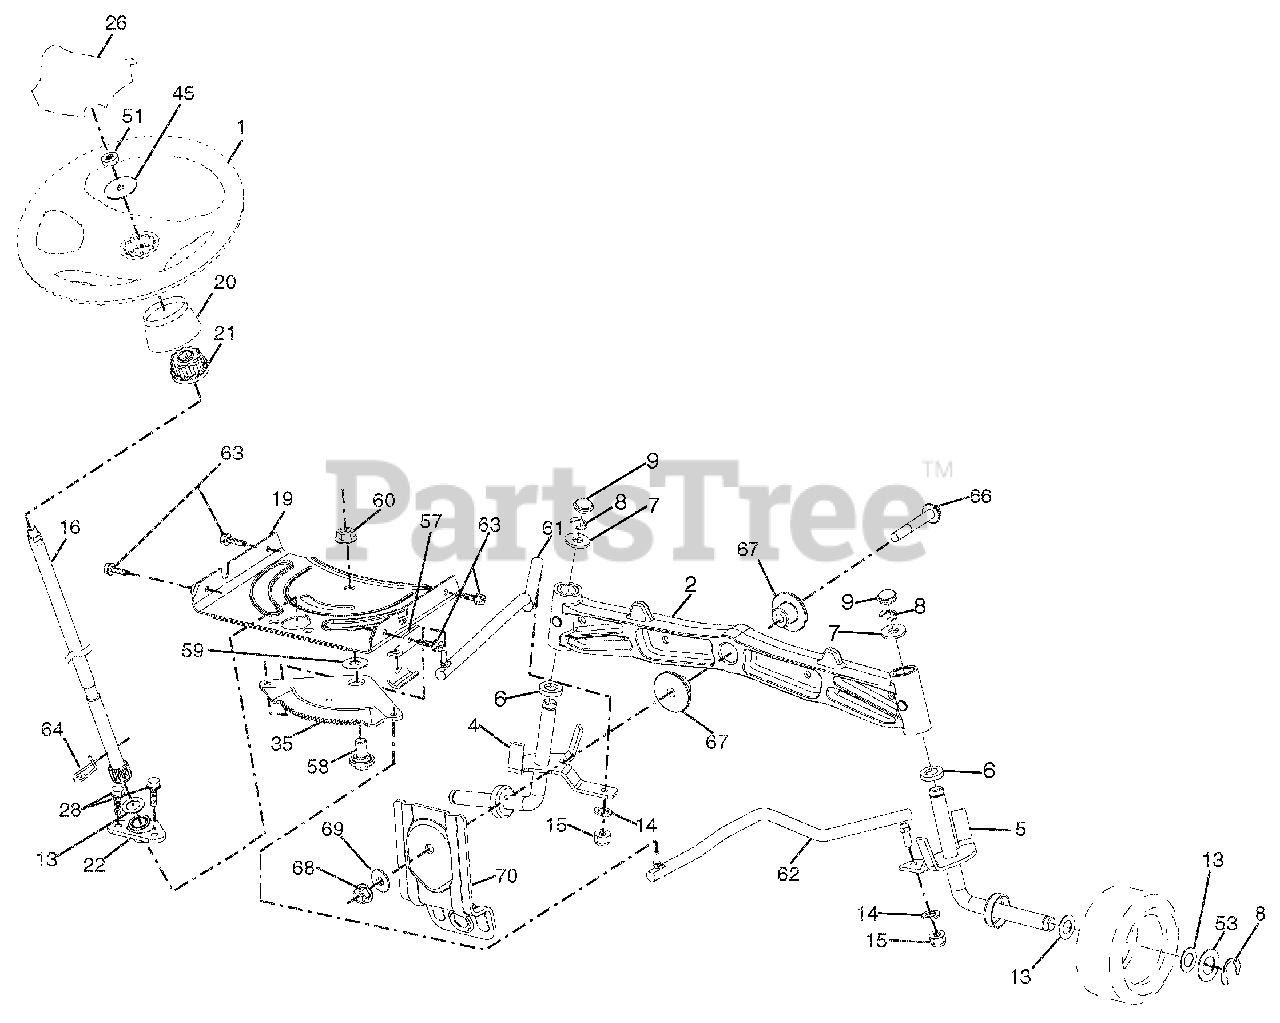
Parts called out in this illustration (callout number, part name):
1	WHEEL STEERING
2	AXLE.CAST IRON
4	SPINDLE.WELDED.LH.15"TEX
5	SPINDLE.WELDED.RH.15"TEX
6	WASHER.THRUST..75 X 1.230
7	WASHER.25/32 X 1-5/8 X 16GA.
8	RING.KLIP.#T5304-75
9	CAP.SPINDLE.FR.TOP.BLK.
13	WASHER.25/32 X 1 1/4 X 16 GA.
14	Washer, Lock 3/8
15	NUT.CROWNLOCK.3/8-24
16	SHAFT.STEER.3/4 TEX.NON-PLATED
19	PLATE.STEER.DDL.NLT/NGT
20	BOOT.STEERING.TEX ELITE.428
21	ADAPTER.WHEEL.STRG..760
22	STEERING SUPT. LOWER
26	CAP.WHL.STRG.HRS/SRS.BLACK
28	SCREW.HEXWSH THDR3/8-16X3/4.BL
35	GEAR SECTOR.PLATE.DDL.NLT/NGT
45	WASHER.9/16ID X 2-3/8OD.12GZIN
51	NUT.HEX.JAM.TOPLOCK.1/2-20 UNF
53	WASHER.HARDEN..793 X 1.637X060
57	BRACKET.UPSTOP.TEX
58	BOLT.SHOULDER.SECTOR.PIVOT.CFM
59	WASHER.THRUST.SECTOR.STEER.NLT
60	NUT.FLANGE LOCK.5/8-11
61	DRAGLINK.LH.BALLSTUD.DDL.
62	DRAGLINK.RH.BALLSTUD.DDL
63	SCREW.5/16-18X3/4.SMGML.TAP/BL
64	RETAINER.CLIP.SPRING.STEERING
66	BOLT.HEX.FGHD.7/16-14 X 3.SERR
67	BUSHING.PM.FRONT AXLE
68	NUT.LOCK.FLANGE.7/16-14.GR5
69	WASHER.1.5 X .505 X .118
70	BRACKET.DECK.SUSPENSION.FRONT
